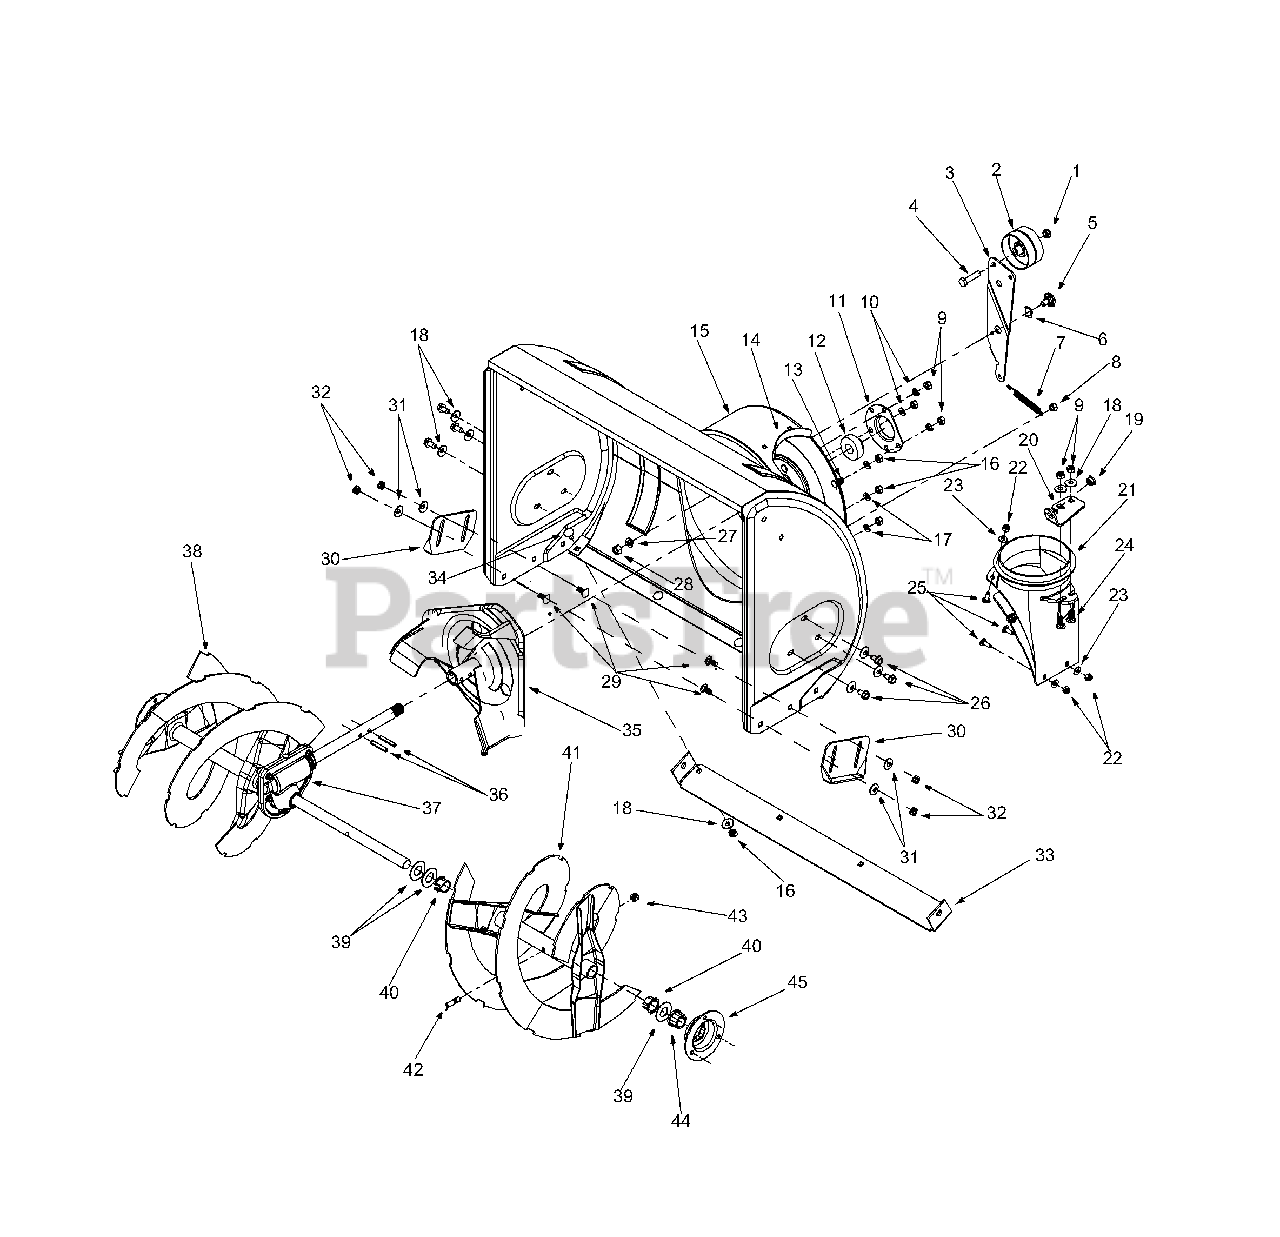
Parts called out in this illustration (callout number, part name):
1	Lock Jam Nut 3/8-24
2	Flat Idler
4	Hex Cap Screw 3/8-24 x 1.50
5	Shoulder Screw
6	Wave Washer
7	Extension Spring
8	Hex Nut 5/16-18
9	Hex Nut 5/16-18
10	Lock Washer 5/16
11	Housing
12	Ball Bearing
13	Carriage Bolt 5/16-18
17	Lock Washer 5/16
18	Bell Washer
19	Bushing
21	Chute Adapter
22	Hex Lock Nut 1/4-20
23	Flat Washer
24	Carriage Bolt
25	Carriage Screw 1/4-20 x .75
26	Hex Washer Screw 5/16-18
27	Lock Washer 3/8
28	Hex Nut 3/8-16
29	Carriage Bolt 5/16-18 x .75
31	Bell Washer
32	Hex Nut 5/16-18
34	Carriage Bolt 5/16-18 x .62
37	22" Gear Assembly D
40	Flange Bushing
42	Shear Bolt 5/16-18 x 1.5
43	Lock Nut 5/16-18
44	Hex Flange Bearing
